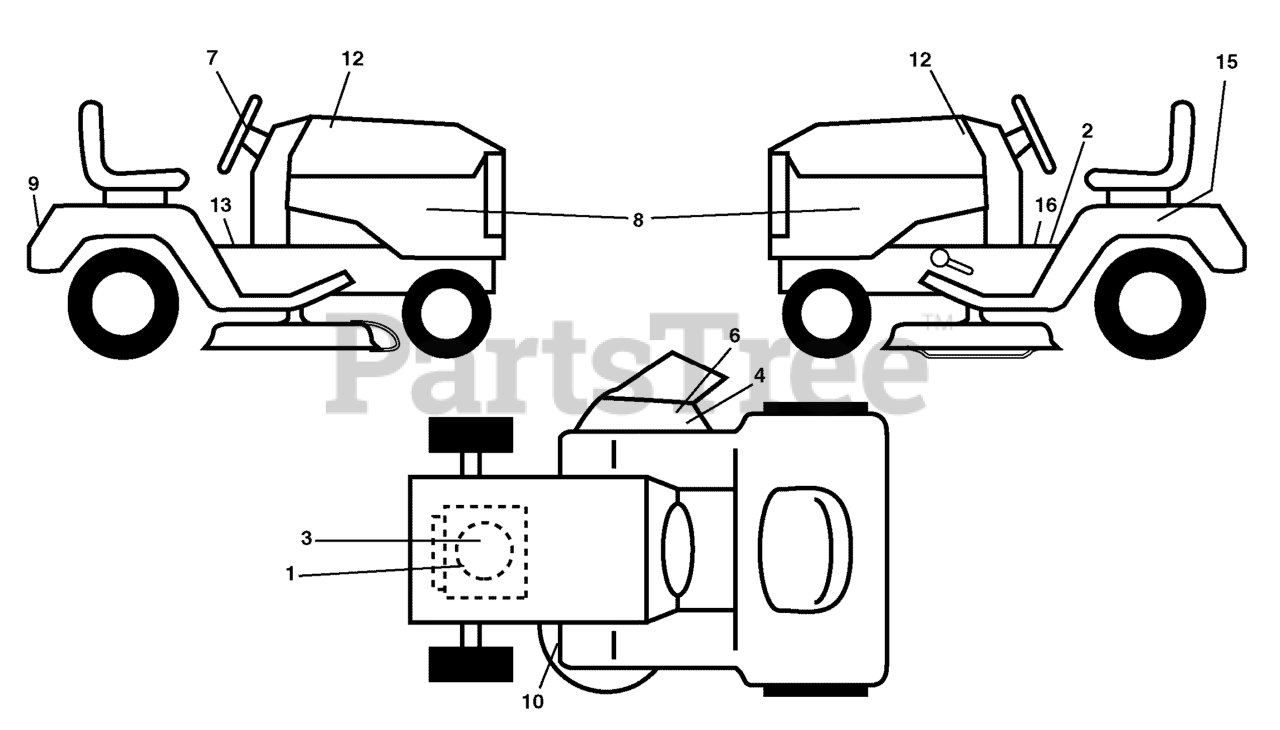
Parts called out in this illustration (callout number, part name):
1	DECAL, Warning Eng Sym
2	DECAL, Warning Symbols
3	DECAL, Engine HP
4	DECAL, Warning Cutfinger
6	DECAL, Cutfinger
7	DECAL, Ins Str Wh
8	DECAL, SDPNL
9	DECAL, Fender
10	DECAL, V-Belt Sch.
12	DECAL, Hood LH/RH Set
13	DECAL, Saddle Brake Parking
15	DECAL, Caution, Battery
16	DECAL, Brake/Clutch Sym.
